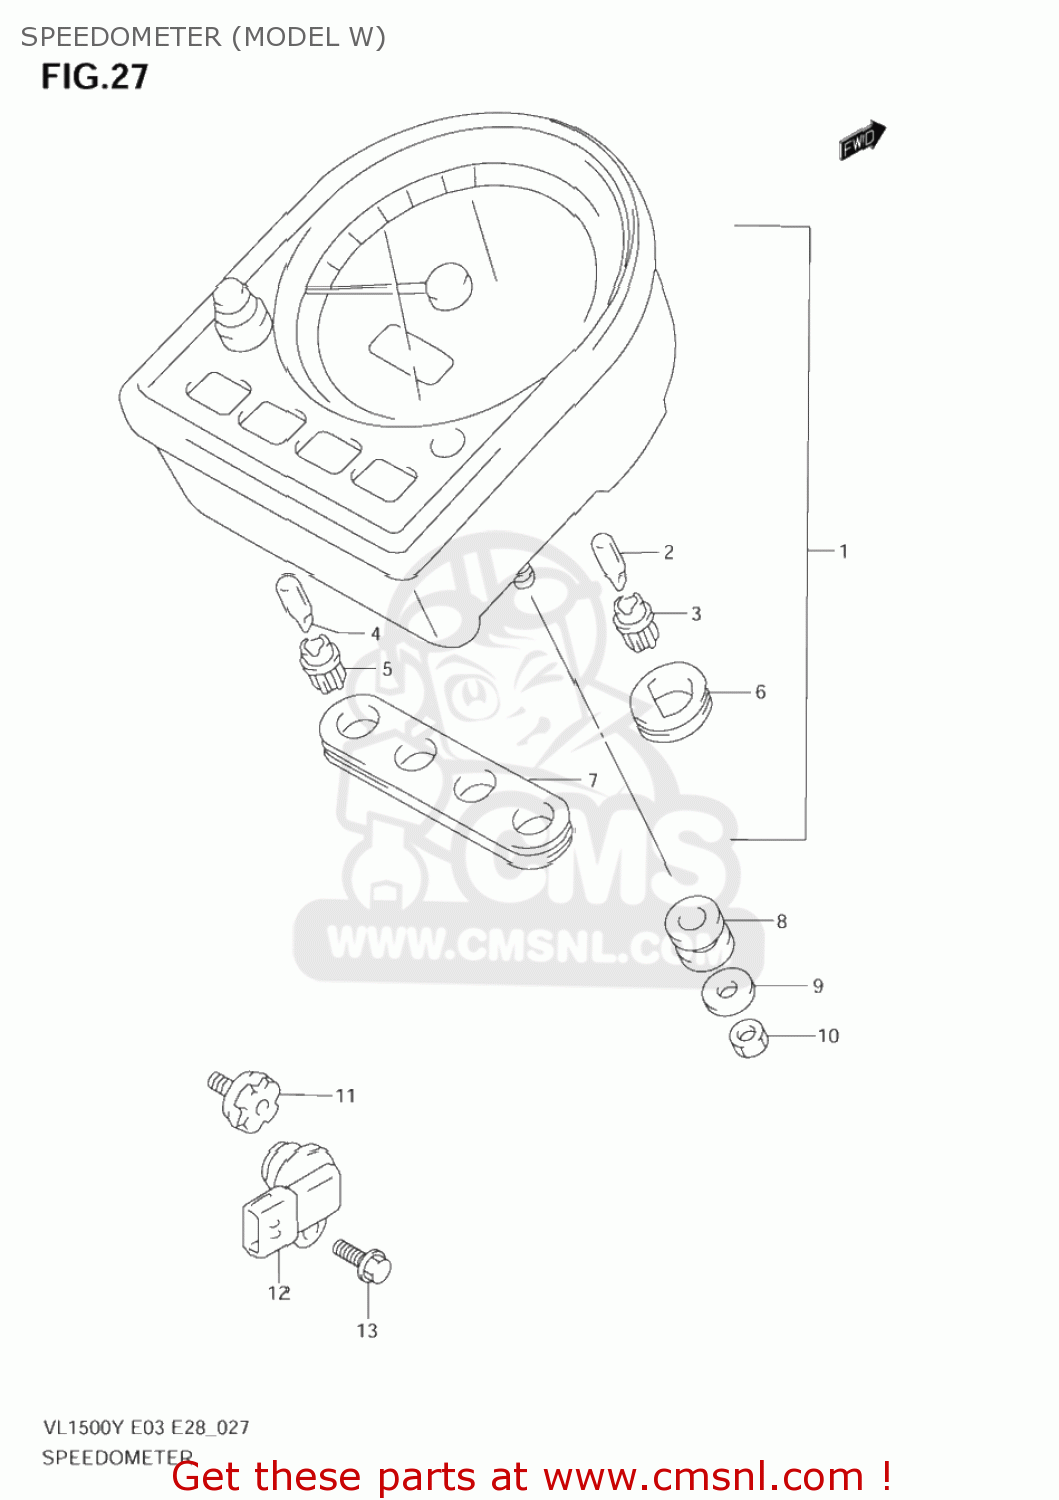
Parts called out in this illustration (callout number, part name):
1	SPEEDOMETER (KILO)
2	BULB(14V,0.84W)
3	SOCKET,BULB
4	BULB(12V1.7W,WB372,T7)
5	SOCKET
6	BLIND,CAP
7	BLIND,CAP
8	CUSHION,METER
9	WASHER(5.5X16X1.2)
10	NUT
11	ROTOR,SPEED
12	SENSOR,SPEED
13	BOLT(6X16)
